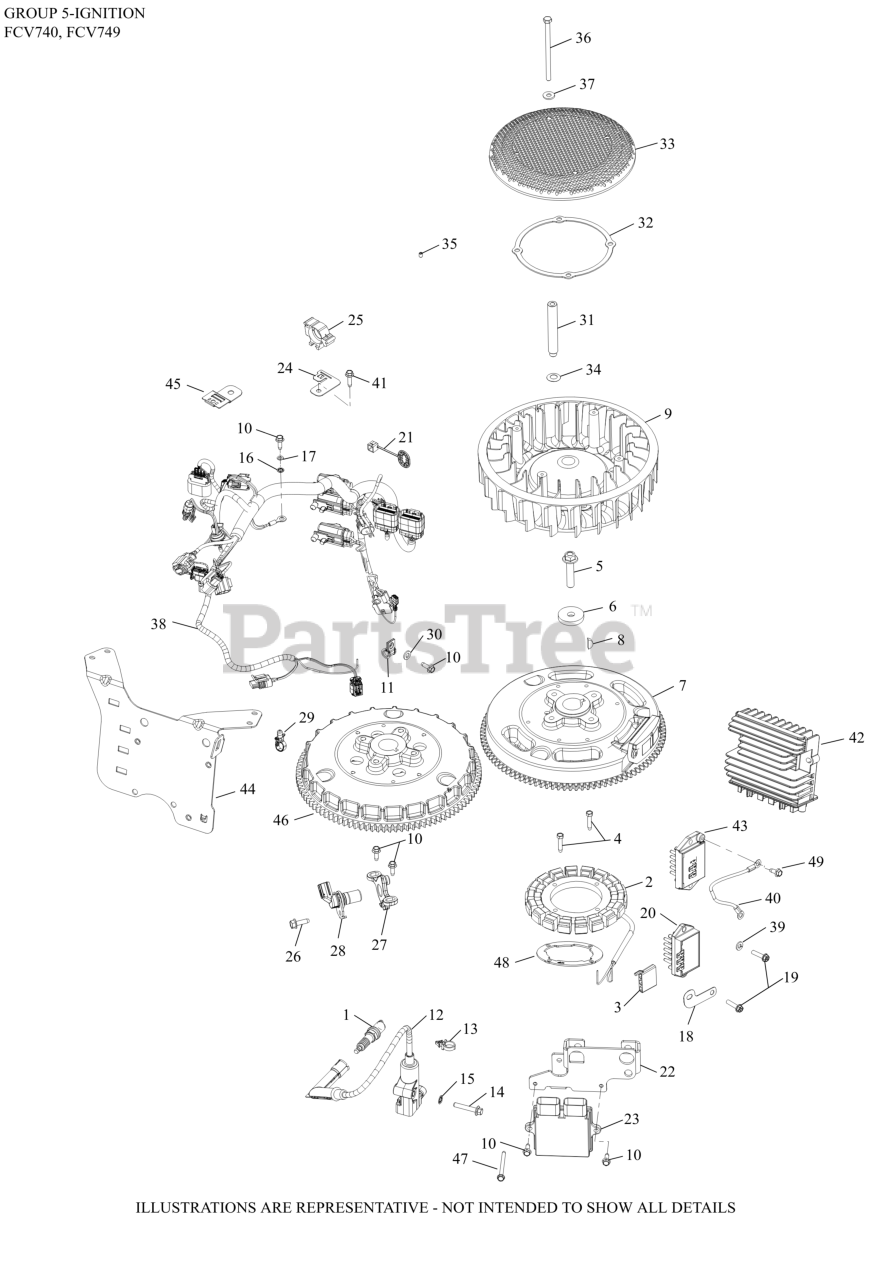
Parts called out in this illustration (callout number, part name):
1	SPARK PLUG, RFI
2	KIT, 15 / 20 AMP STATOR
3	CONNECTOR
4	SCREW, THREAD FORMING
5	SCREW, FLG M10X1.5X45-USE 25 086 361-S
6	WASHER, FLAT 13/32"
7	FLYWHEEL ASSEMBLY
8	KEY, 3/16" X 5/8"
10	SCREW, THREAD FORMING
12	COIL, IGNITION - EFI (RFI/EMC)
13	CLIP, SNAP-IN-USE 25 018 05-S
14	SCREW, FLG (BLACK) M6X1.0X34
15	WASHER, INT TOOTH LOCK 1/4"
16	WASHER, INT TOOTH LOCK #10
19	SCREW, HEX FLANGE HI-LO
21	CAP, CONNECTOR
22	BRACKET, ECU
23	MODULE, ECU FLEX FUEL
24	CLIP USE 25 154 21-S
25	KIT, MOUNTING CLIP
26	SCREW, THREAD FORMING
27	BRACKET, SENSOR SPEED
28	SENSOR, SPEED
30	WASHER, FLAT 1/4" (O.D. 1/2")
32	RING, SUPPORT
33	SCREEN, GRASS
34	WASHER, SPRING 10 MM
35	SCREW, SKT SET #10-24X1/4"
36	SCREW, CAP M6X1.0X99.5
37	WASHER, FLAT 1/4" (O.D. 5/8")
41	SCREW, THD FRM-USE 25 086 473-S
NI	MODULE, ECU
NI	RETAINER, WIRE HARNESS
NI	SCREW, THREAD FORMING
NI	REGULATOR, RECT (20-30AMP, FW W/OVP)
